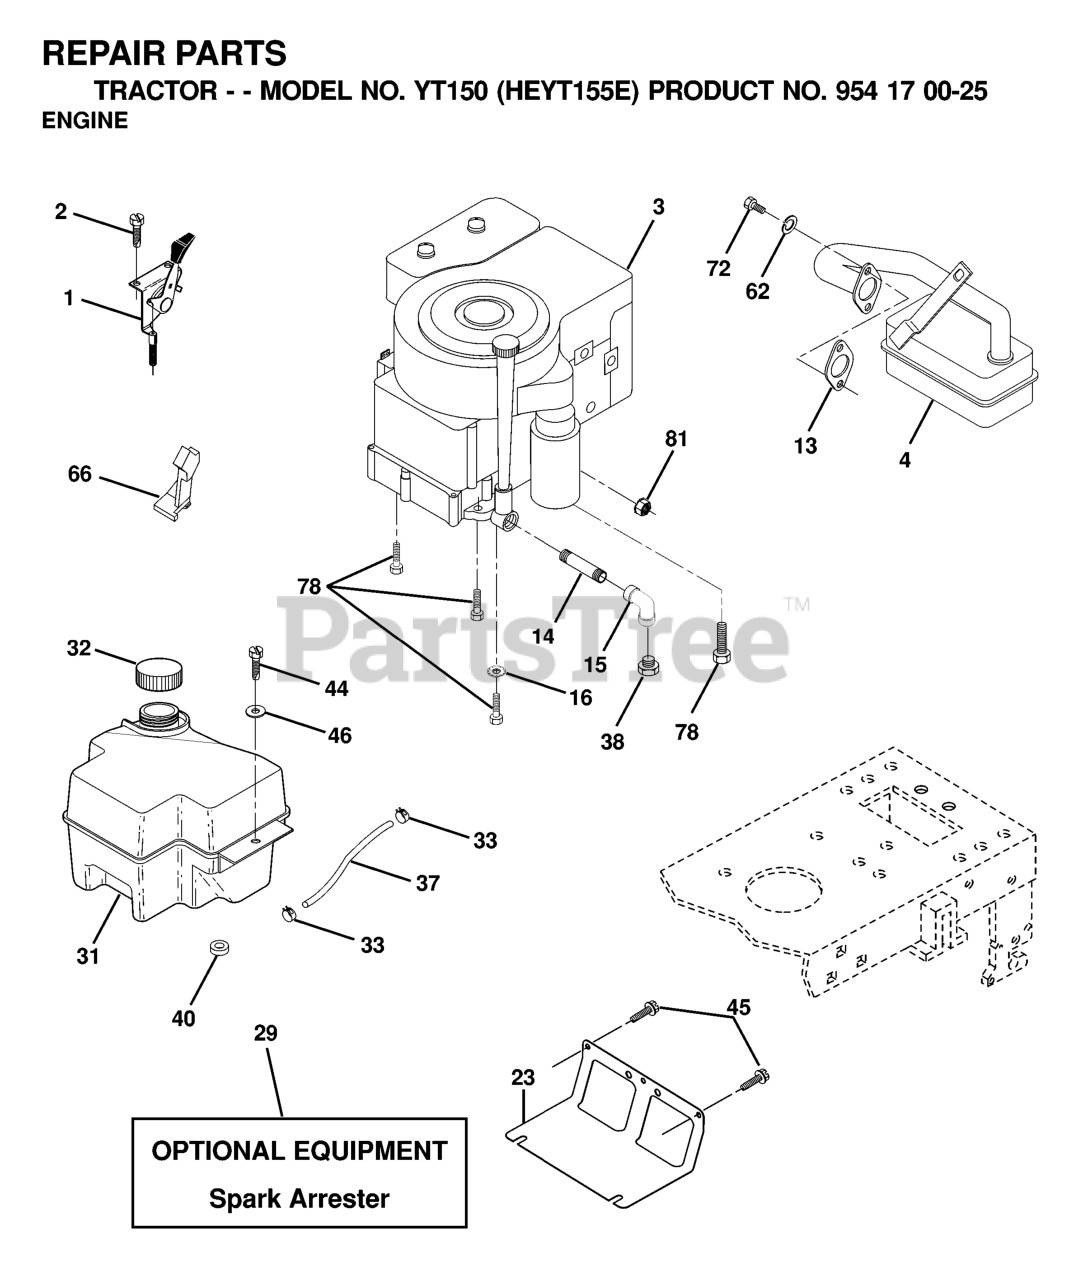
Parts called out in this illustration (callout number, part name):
1	CONTROL
2	SCREW LT
4	MUFFLER.LT.BRIGGS.14HP.IC/OHV
13	REPL BY 532 27 22-93
14	Nipple Pipe 3/8 Npt X 3-1/2
15	ELBOW
16	LOCKWASHER
23	SHIELD.BROWNING.DBR.GUARD
29	KIT.SPARK ARRESTOR 794945 B&S
31	FUEL TANK
32	FUEL CAP
33	HOSE CLAMP
37	LINE.FUEL.20
40	BUSHING.SNAP.NYL.BLK.
44	SCREW HEXWSHR 1/4-20X3/4
45	SCREW, 3/8-16X3/4
62	WASHER.LOCK.HVY.HLCL.SPR.5/16
66	STOP THROTTLE
72	SCREW
78	SCREW.3/8-16
81	NUT
